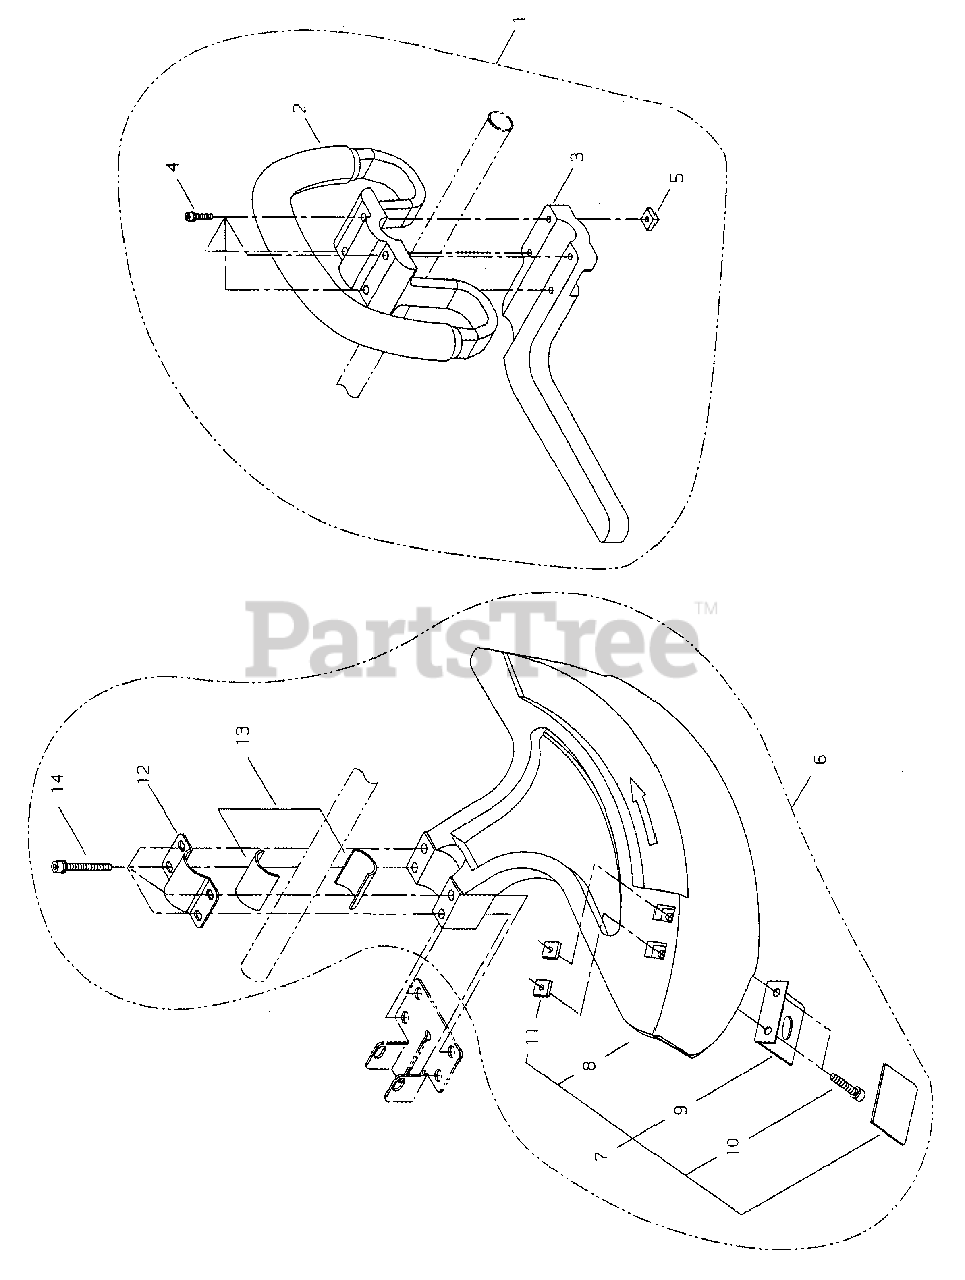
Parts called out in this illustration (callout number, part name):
1	HANDLE KIT - FRONT
2	HANDLE
3	BAR, BARRIER
4	SCREW - 5X35
5	NUT - 5
6	DEBRIS SHIELD KIT
7	DEBRIS SHIELD ASSY
8	DEBRIS SHIELD ASSY
9	KNIFE, TRIMMER LINE
10	SCREW - 5X22
11	NUT - 5
12	CLAMP, UPPER
13	SPACER
14	SCREW - 5X45
